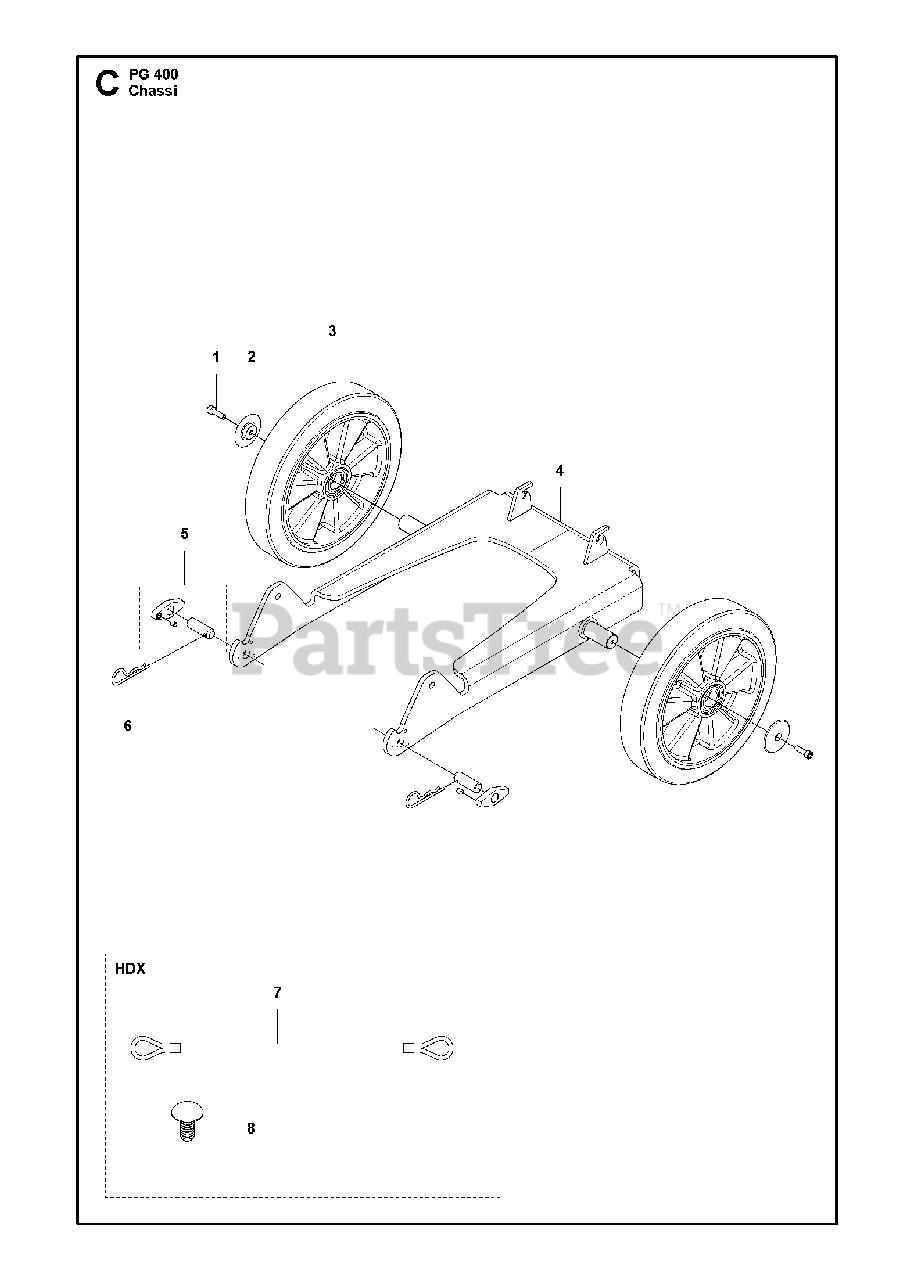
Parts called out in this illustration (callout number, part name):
1	SCREW IHSCM
6	SPRING COTTER
8	RIVETHDX variant only
